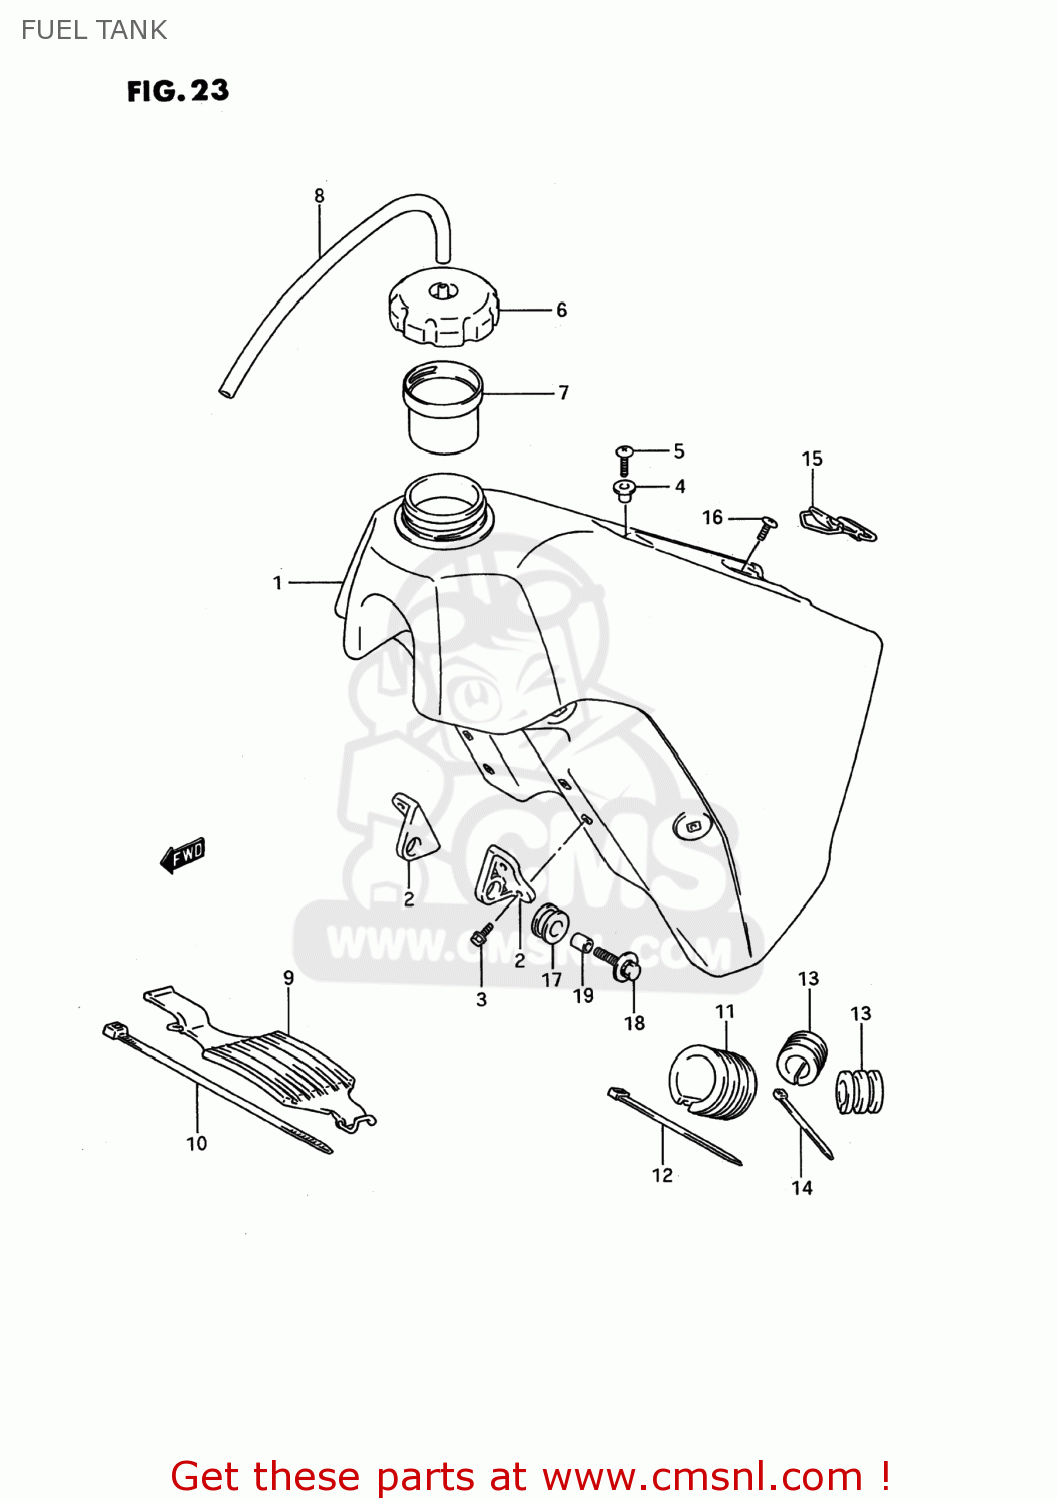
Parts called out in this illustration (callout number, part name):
1	TANK ASSEMBLY,FUEL
2	BRACKET,FUEL TANK FR
3	BOLT
4	HOOK,SEAT FR
5	SCREW
6	CAP ASSY,FUEL TANK
7	TUBE,FILLER INLET
8	HOSE(5X8.2X600)
9	CUSHION,FUEL TANK NO.1
10	CLAMP
11	CUSHION,FUEL TANK NO.2
12	CLAMP(L:300)
13	CUSHION,FUEL TANK NO.1
14	CLAMP(L:145)
15	BAND,FUEL TANK RR
16	SCREW
17	CUSHION
18	BOLT(8X30)
19	SPACER (8.8X12X13.5)
